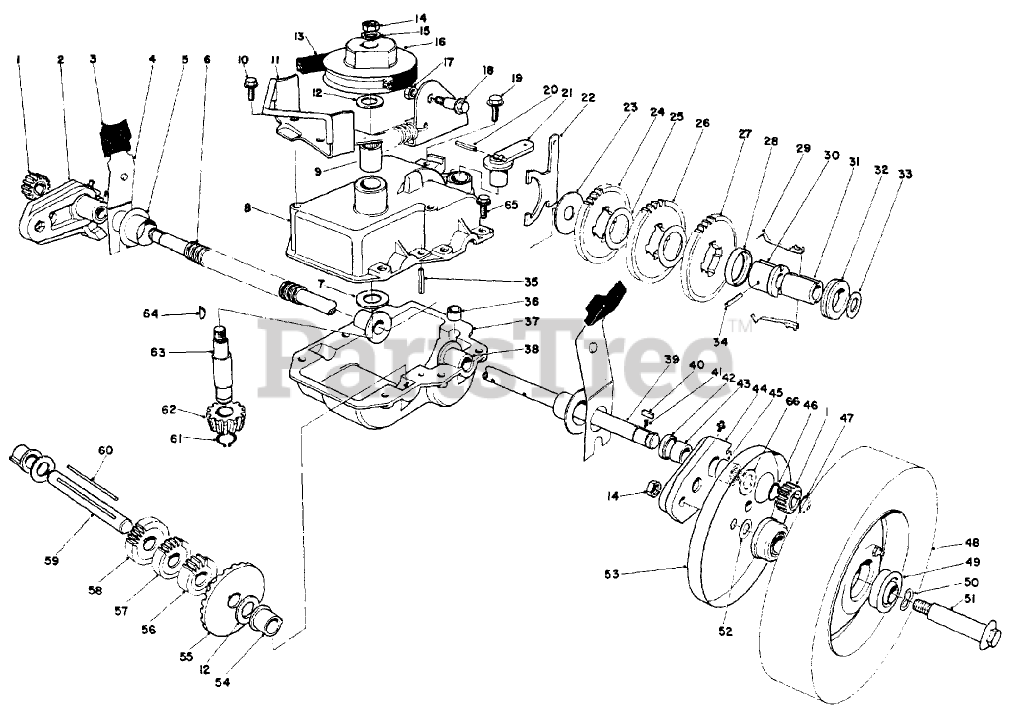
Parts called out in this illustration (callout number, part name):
1	GEAR-PINION
3	KNOB-ARM
5	CAP-END
6	CONDUIT-CONVOLUTED, SPLIT
8	DISC PRC4
12	WASHER-THRUST
13	V-BELT
15	WASHER-FLAT
16	PULLEY
19	SCREW-THD ROLL, HWH
20	PIN-SPRING
21	LEVER-SHIFT
23	WASHER
24	GEAR-38T
25	WASHER
27	GEAR-42T
31	SLEEVE
32	COLLAR-SHIFT
33	WASHER-PLAIN
35	ROLL PIN 3/16 X 1 IN
36	BUSHING-YOKE
40	KEY RECTANGULAR
41	SPRING-COMPRESSION
43	Bushing
46	RING-EXT GRIP
47	RING-RETAINING
49	BEARING-BALL
50	SPRING WASHER
51	WHEEL BOLT
52	WASHER
56	14 T GEAR
58	GEAR-18T
61	RING-RETAINING
62	PINION-BEVEL
64	KEY-WOODRUFF
65	SCREW-HWH, THREAD ROLL
